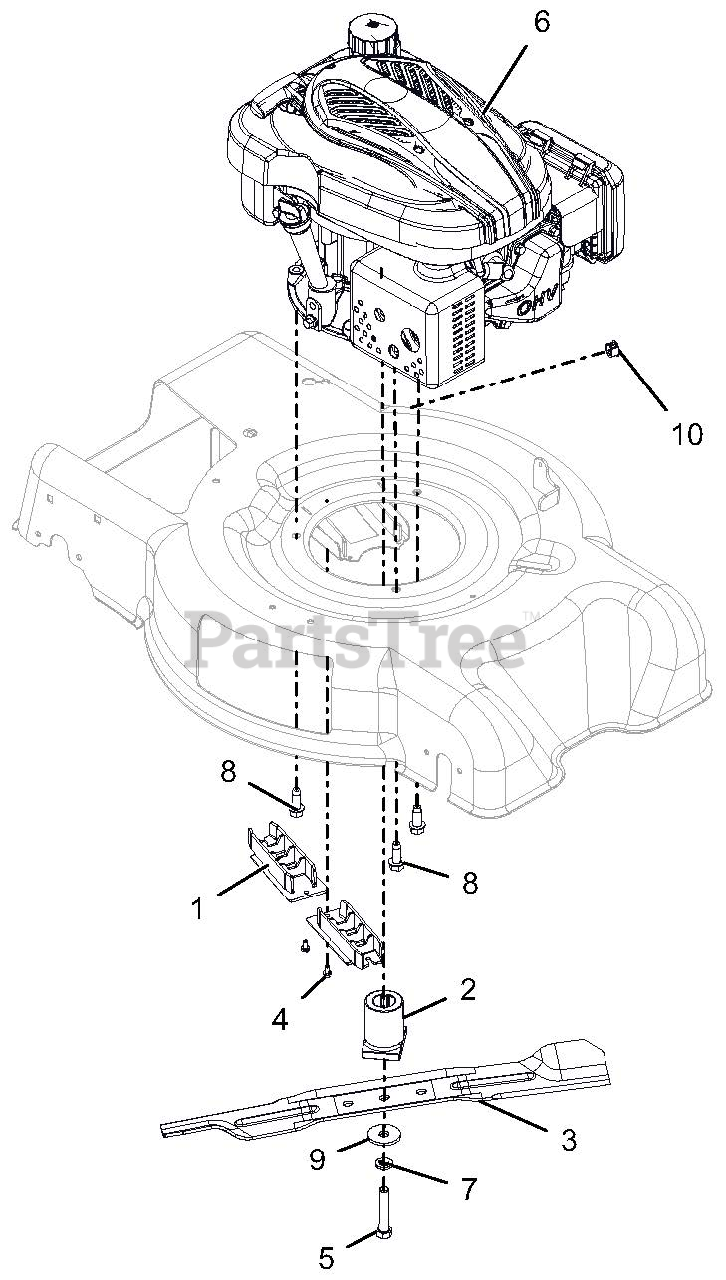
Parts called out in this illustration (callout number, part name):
1	GUIDE, BELT INNER
2	ADAPTER, BLADE
3	BLADE, MOWER 21" HIGH LIFT
4	SCR-TAP 10-24X.375 PRE-COAT 80
5	@BLT-HEX .4375-20X2.25 GR8 YWZ
6	ENGINE, LONCIN 159CC VERT.
7	@WSHR-LK .44X.109 REG YWZC
8	@SCR-TAP .38-16X1.00 HWH TR YZ
9	WSHR-FL-STL .4375X1.50X.125 YZ
10	PLUG, DOME-BLACK, .625 DIA
